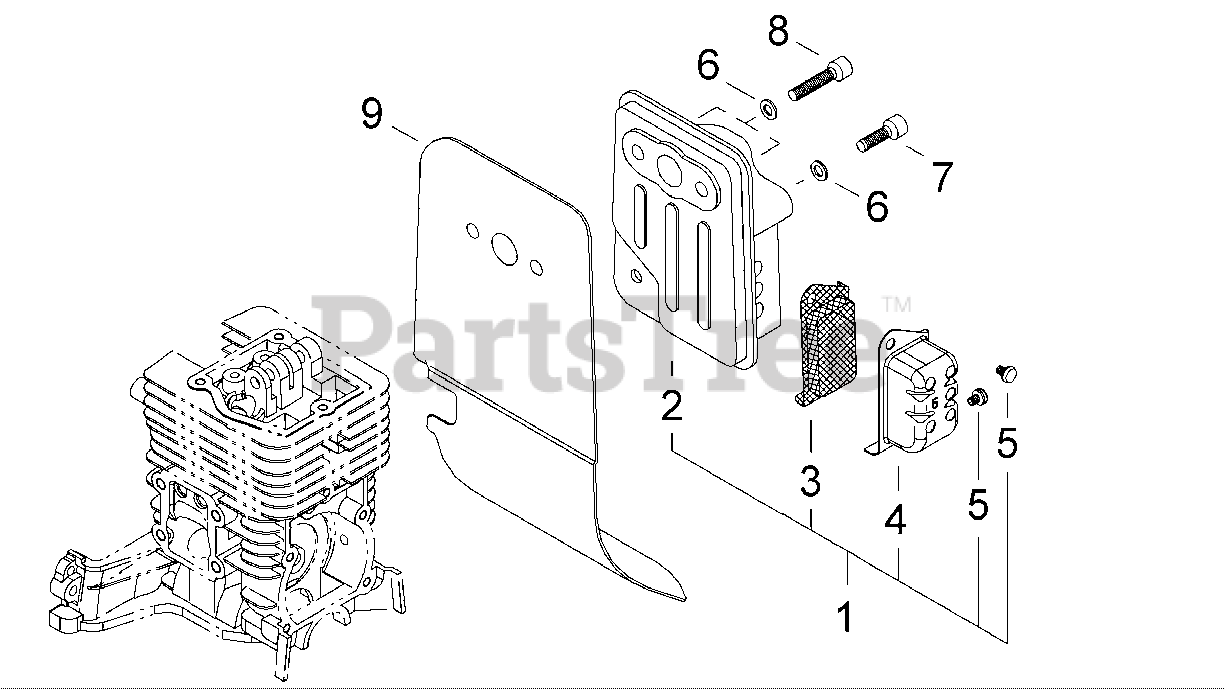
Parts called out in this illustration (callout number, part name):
1	MUFFLER ASSY
2	MUFFLER
3	SCREEN, SPARK ARRESTER
4	GUIDE, EXHAUST
5	SCREW M4×6
6	WASHER, FLAT 5.5×10×0.8
7	BOLT 5×16
8	BOLT M5×25
9	HEAT SHIELD, EXHAUST
